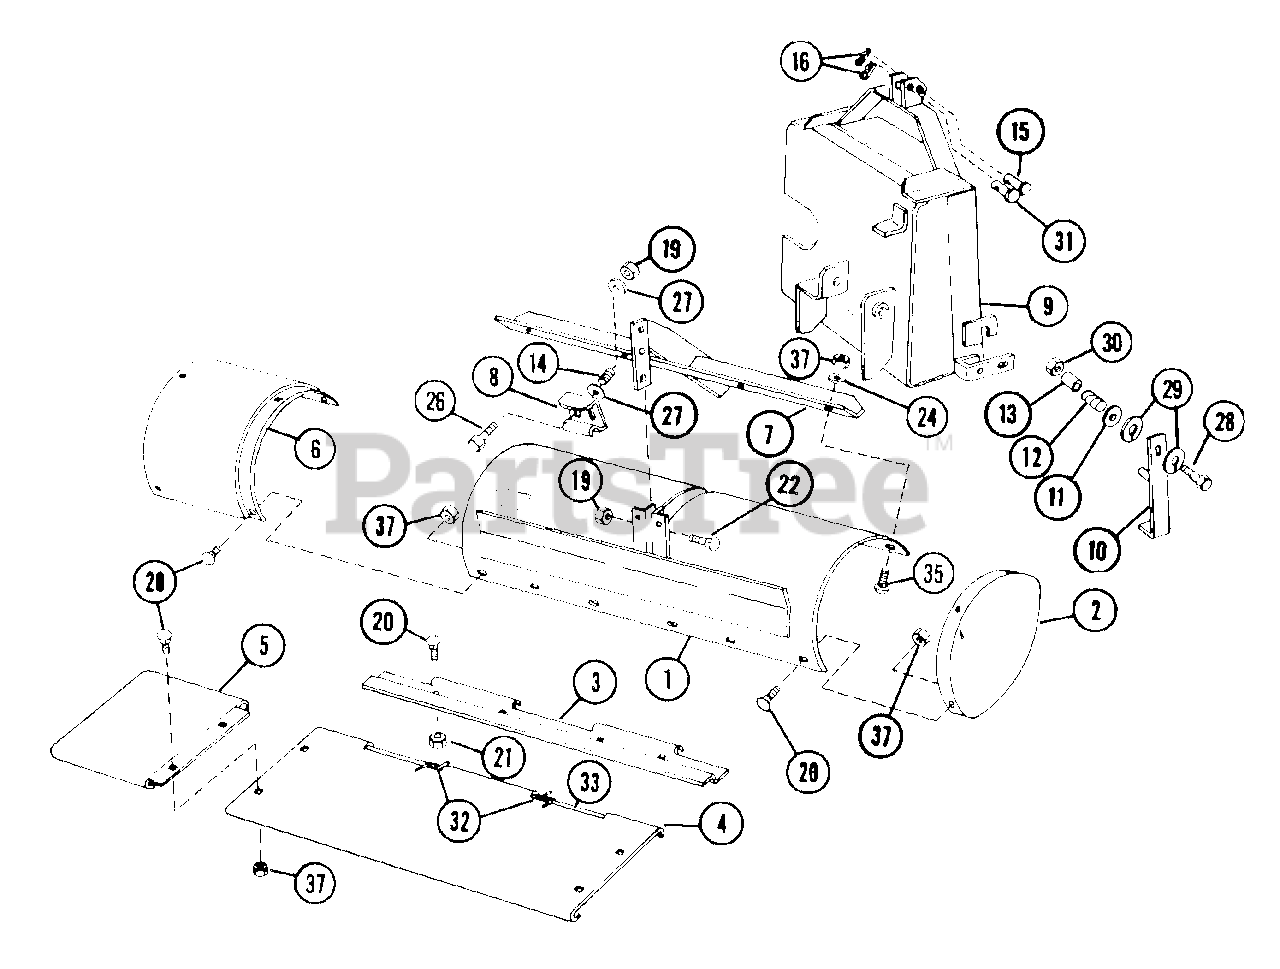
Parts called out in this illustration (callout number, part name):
1	SHROUD ASSEMBLY
2	SHROUD COVER
3	HINGE PLATE
4	LEVELER BLADE
5	BLADE LEVEL EXTENSION
6	SHROUD EXTENSION
7	SHROUD BRACE
9	TILLER FRAME
10	KICK STAND LEG
11	SPACER .406X1.500X.188
12	SG-COMP .70X.68X.68
13	SPACER .384X.500X.625
14	SG-COMP .059X.43X1.00 WLD??
15	CLEVIS PIN
16	PIN-HAIR INT .09X.188 PL
19	NUT-LK TOP .250-20 PL
20	BLT-RDHDSQNK .31-18X.50 GR5 PL
21	NUT-LK .312-18 GR A PL
22	BLT-RDHDSQNK .25-20X.75 GR5PL
24	WSHR-FL-STL.344X.688X.065PL
26	BLT_HEX .25_20X1.75 GR5
27	WSHR-FL-STL.281X.62X.065 PL
28	BLT-HEX .38-16X2.25 GR2
29	WSHR-LK .375X.094 MED PL
30	NUT-HEX .375-16
31	CLEVIS PIN
32	SG-TORS .090X.37X.63
35	BLT-RDHDSQNK.31-18X.75GR5SHTPL
37	NUT-CROWN .312-18 PL
38	WSHR-FL-STL .781X1.250X.059 PL
